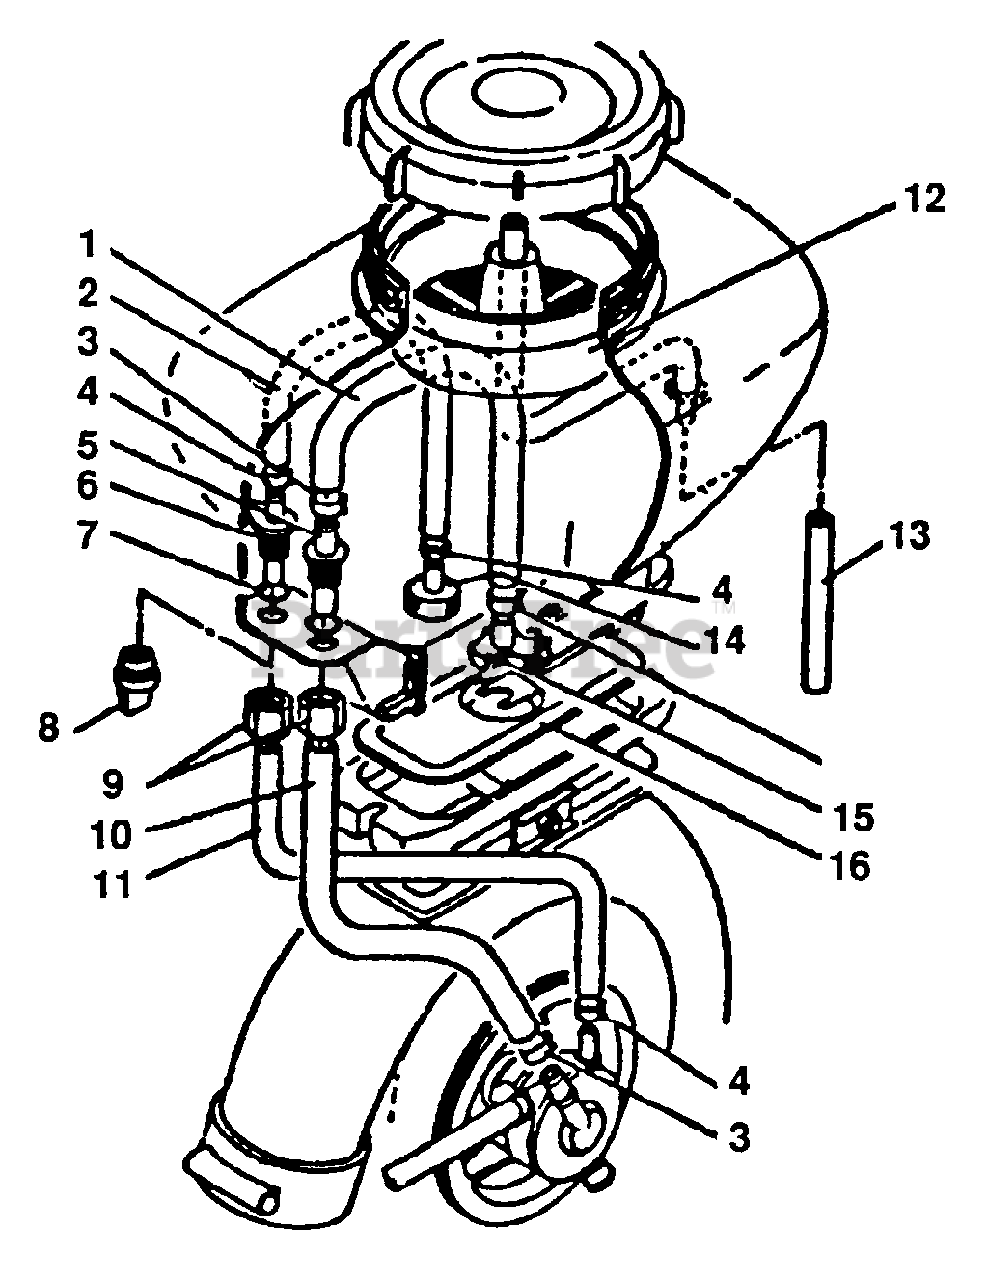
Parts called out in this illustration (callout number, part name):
1	PIPE
2	HOSE, FLUID
3	CLIP - 14
4	CLAMP
5	CONNECTOR, PIPE
6	FITTING, GREASE
7	O-RING 3×13
8	PLUG, RUBBER
10	PIPE
11	HOSE, FLUID
12	FILTER, TANK
13	PIPE, OUTER PRESSURE 7×11×170L
14	NIPPLE
15	MOUTH, SUCTION
